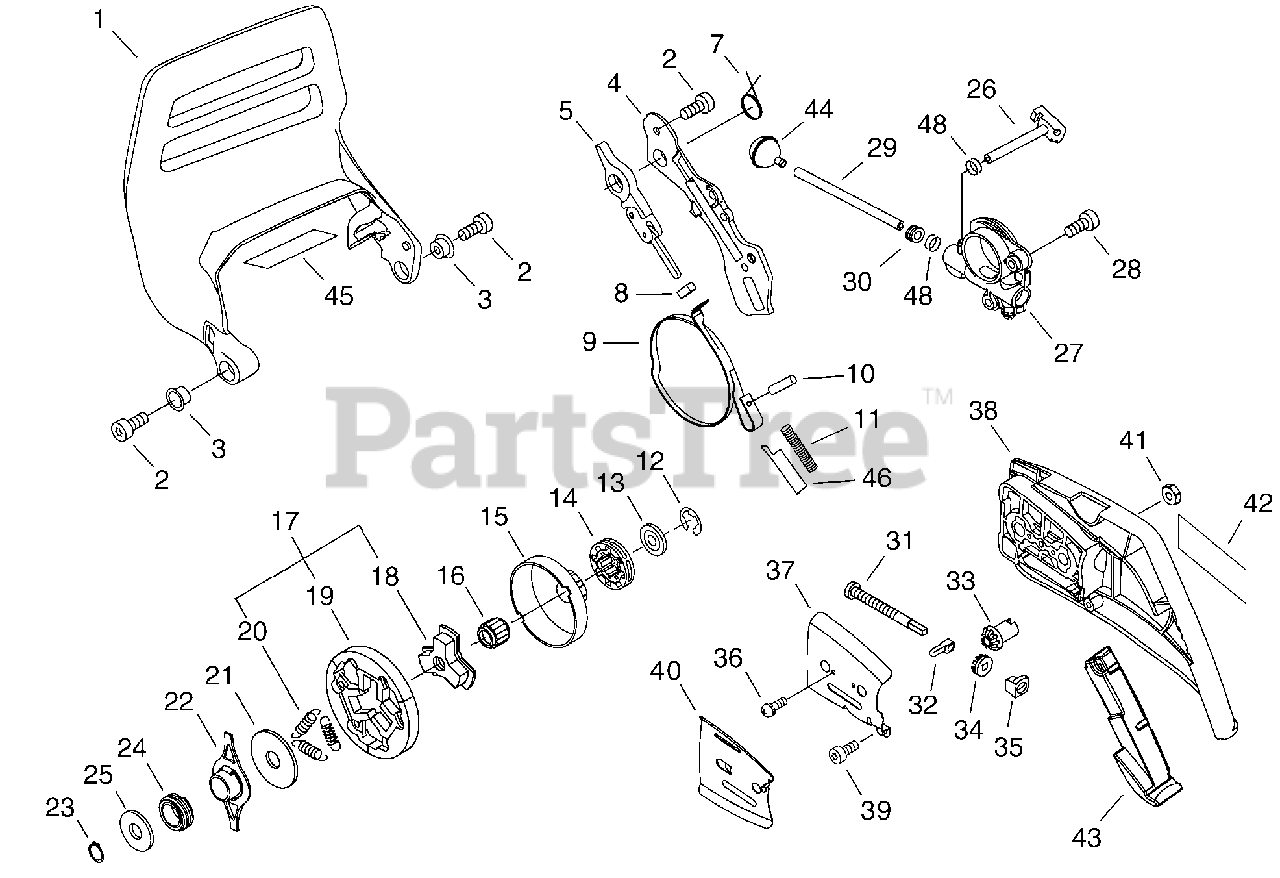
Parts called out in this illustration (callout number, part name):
1	BRAKE, CHAIN
2	BOLT, TORX 5×16
3	COLLAR 11.2×16.2×T0.6
4	COVER, BRAKE
5	CONNECTOR, BRAKE
7	SPRING, TORSION
9	BAND, BRAKE
11	SPRING, COMPRESSION Ø12×70.5
12	RING, SNAP Ø8 T: 1.2
13	WASHER 10×28.5×3.5(0.8)
14	SPROCKET, RIM 3/8"×7T
15	DRUM, CLUTCH
16	BEARING, NEEDLE 10
17	CLUTCH ASSY
18	HUB, CLUTCH
19	SHOE SET, CLUTCH (3PCS)
20	SPRING, TENSION
21	PLATE, CLUTCH
22	COLLAR 15×19×73
23	RING, RETAINING 15
24	GEAR, WORM
25	WASHER 15.5×22.5×0.5
26	PIPE, OIL
27	AUTO-OILER ASSY
28	BOLT, TORX 4×12
29	PIPE, FUEL 3×6×210 BLACK
30	GROMMET
31	SCREW, CHAIN TENSION
32	TENSIONER, CHAIN
33	GEAR, BEVEL
34	GEAR, BEVEL
35	COLLAR 8
36	SCREW 3×6
37	PLATE, GUIDE - OUTER
38	GUARD, SPROCKET
39	BOLT, TORX 4×12
40	PLATE, GUIDE - INNER
41	NUT 8
42	LABEL, ECHO
43	CUSHION, CLUTCH COVER
44	FILTER, OIL
45	SHIELD, HEAT 75×27×0.15
46	PLATE, SIDE
48	CLIP 6 MM
